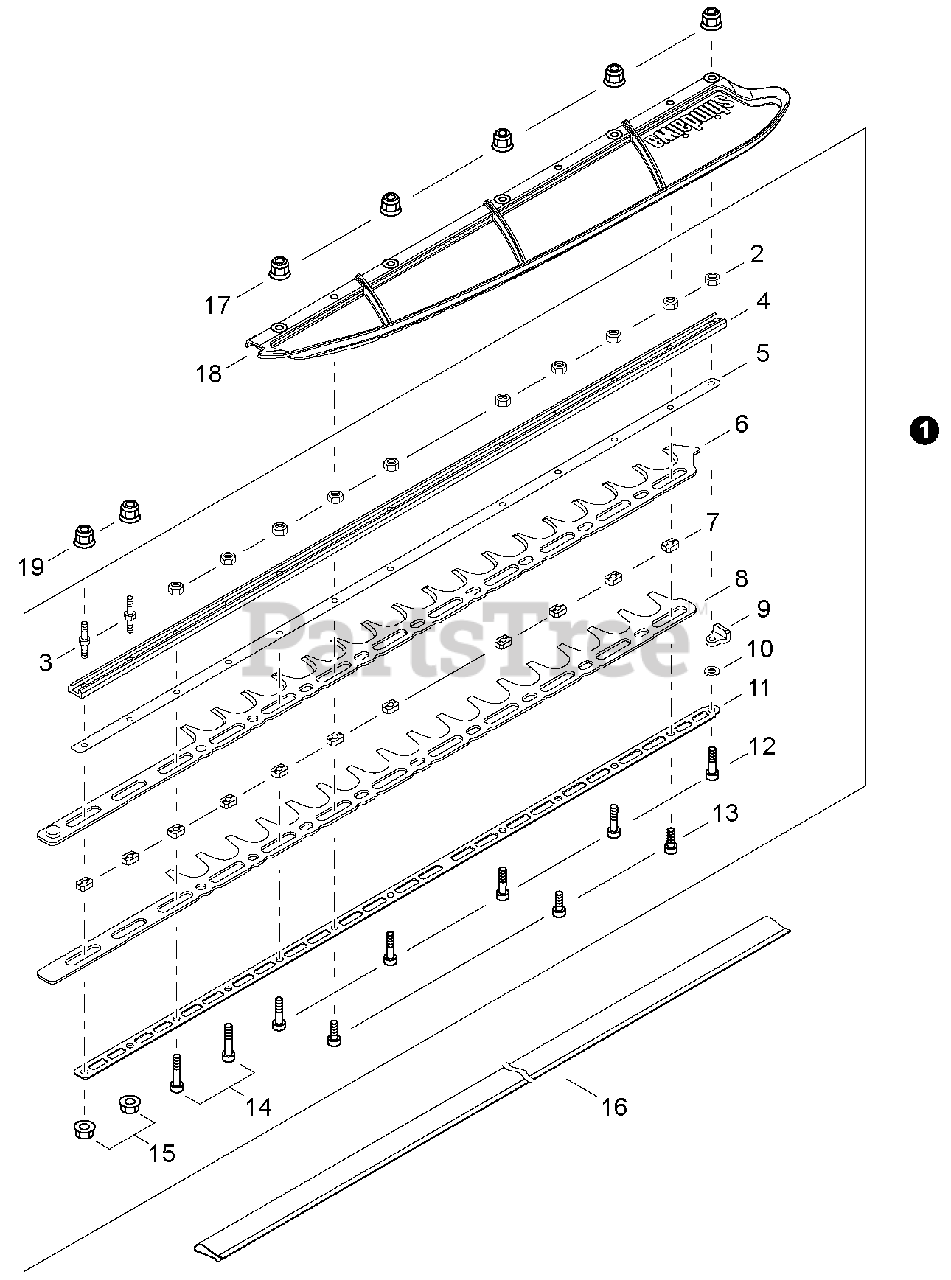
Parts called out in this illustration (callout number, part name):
1	BLADE ASSY - 30" (76cm)
4	SUPPORT, CUTTER - 30" (76cm)
5	SUPPORT, CUTTER - 30" (76cm)
6	BLADE - 30" (76cm)
8	BLADE - 30" (76cm)
11	SUPPORT, CUTTER - 30" (76cm)
12	SCREW - 5X25
13	SCREW - 5X16
14	SCREW - 5X30
15	NUT - 5
16	COVER, BLADE
17	NUT - 5
18	DEFLECTOR, DEBRIS
19	NUT - 5
